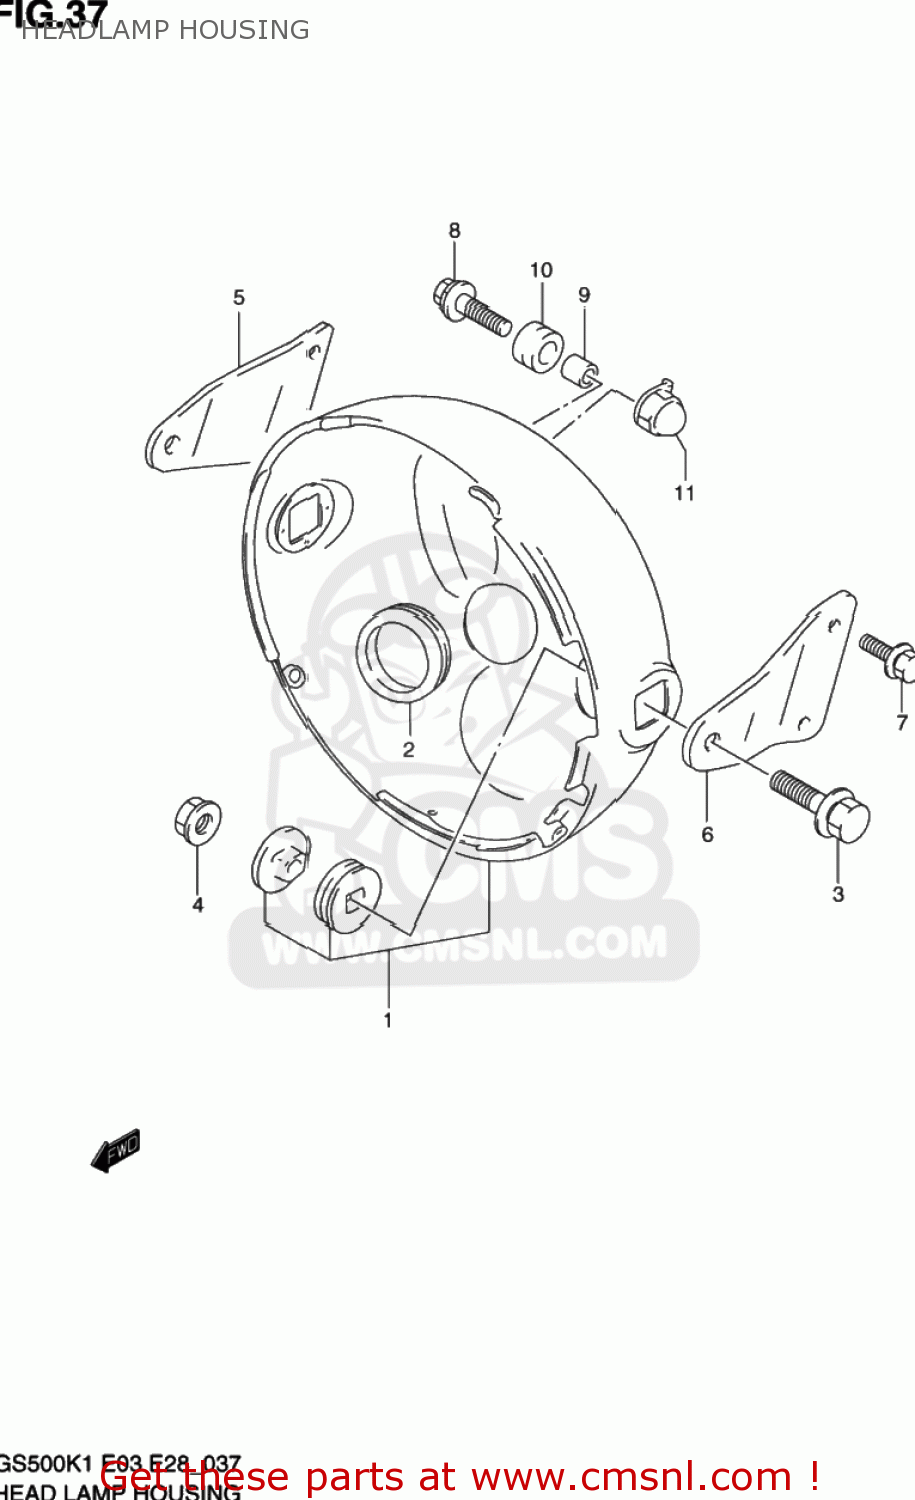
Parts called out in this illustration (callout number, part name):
1	HOUSING,HEADLAMP
2	GROMMET
3	BOLT
4	NUT
5	STAY,HEADLAMP HOUSING,R
6	STAY,HEADLAMP HOUSING,L
7	BOLT
8	BOLT
9	SPACER(6.5X10.5X12)
10	CUSHION
11	PLATE,HEADLAMP
